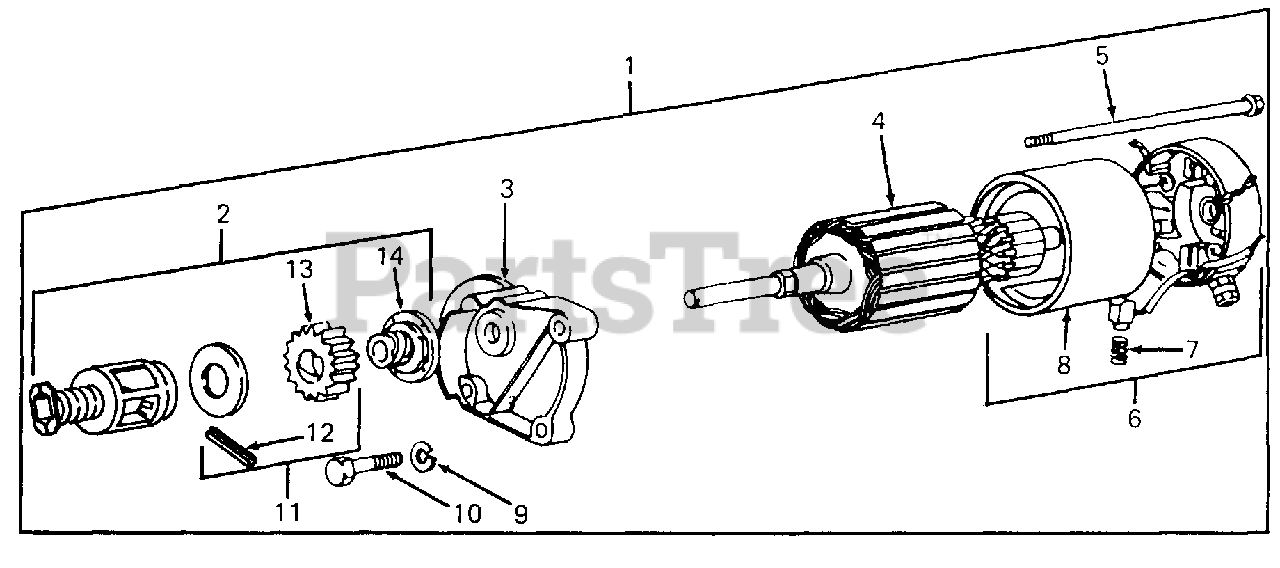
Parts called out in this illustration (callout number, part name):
1	Motor and Drive Assembly
2	Starter Drive Group
3	End Cap Assy, Drive
4	Armature Assy
5	Thru Bolt
6	End Cap Assy, Commutator
7	Brush Assy
8	Housing Assy
9	Lockwasher
10	Screw, Hex Hd 5/16-18 X 1-1/2
11	Pinion Spring Kit
12	Pin, Roll
13	Gear
14	Clutch Assy
